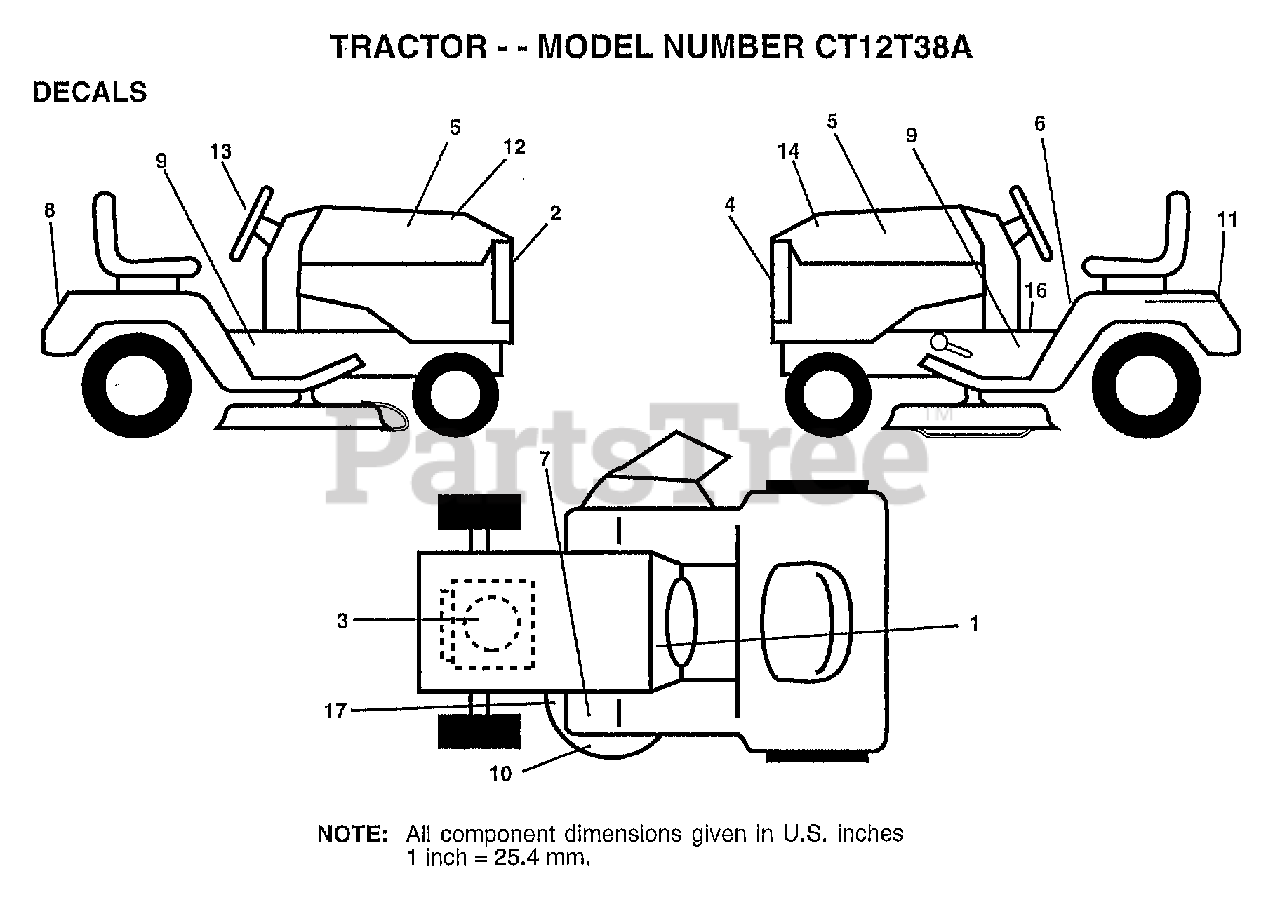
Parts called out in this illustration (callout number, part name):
1	"DECAL-OPER,GEAR D"
2	GRILL DECAL
3	DECAL, HP, ENGINE
5	DECAL.HOOD.INS.
6	"DECAL DANGER,FEND"
8	FENDER DECAL
9	DECAL CHASSIS SPEED DECK
11	DECAL.BATRY.3-3908
12	DECAL HOOD RH RLY
13	"DECAL,STR WHL"
14	DECAL HOOD LH RLY
16	DECAL BRAK PARK
17	DECAL
